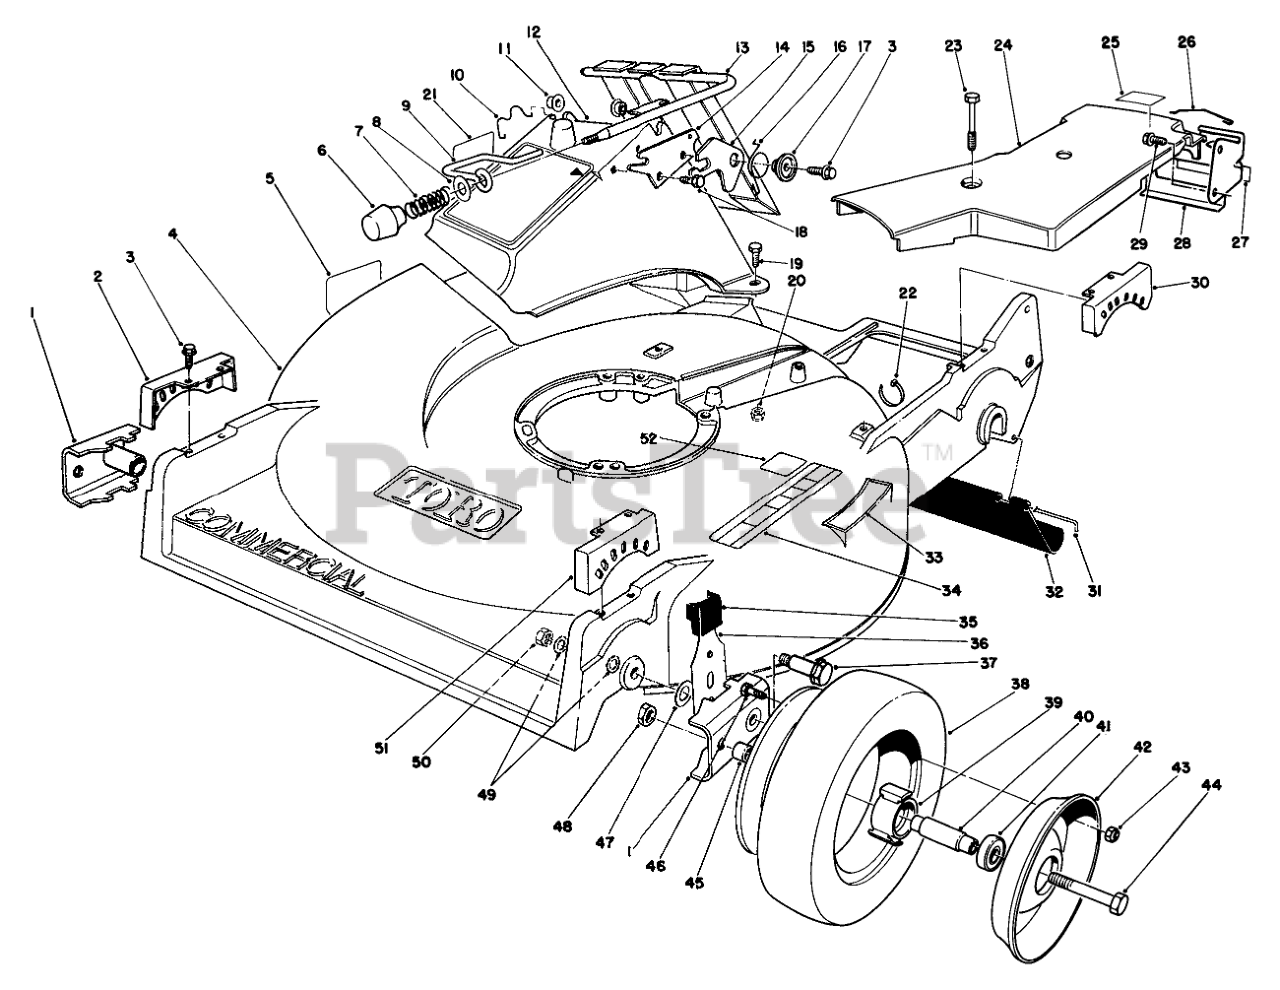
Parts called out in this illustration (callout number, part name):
1	ARM-PIVOT, FRONT
2	QUADRANT-FRONT, RH
3	SCREW-HWHTF
4	Housing-Commercial (Incl. Ref. #5, 33 & 34)
5	Decal Danger
7	COMPRESSION SPRING
8	WASHER-FLAT
9	DOOR LATCH
10	DOOR RETAINER
11	BUSHING-NYLON
12	DISCHARGE CHUTE B
13	DOOR & HANDLE WA
14	DOOR LATCH PLATE
15	SAFETY LATCH
16	TORSION SPRING
17	DOOR SPACER
18	SCREW-HWH
19	SCREW-HH
20	NUT-LOCK, NI
21	DECAL - DANGER
22	TIE-CABLE
23	SCREW-HHFTF
24	COVER-BELT
25	Label-Grease
26	RETAINER-CABLE
27	DECAL-POSITION, GEAR
28	BRKT-TRACTION ADJ.
29	SCREW-HWHTF
30	QUADRANT-REAR, LH
31	ROD-SHIELD
32	SHIELD-TRAILING
33	DECAL - STEP PAD INT'L
34	Decal-Safety Instructions
35	KNOB-ARM
36	FRONT SPRING ARM ASM
37	WHEEL BOLT
39	HUB-BEARING
40	SPACER-BEARING
41	BEARING-WHEEL
42	Wheel-Half
43	NUT-LOCK, NI
44	SCREW-HH
45	SPACER-WHEEL
46	SCREW-HH
47	WASHER-THRUST
48	NUT-LOCK, CONE
49	WASHER
50	Nut
51	QUADRANT-FRONT, LH
52	Decal-Noise Level
